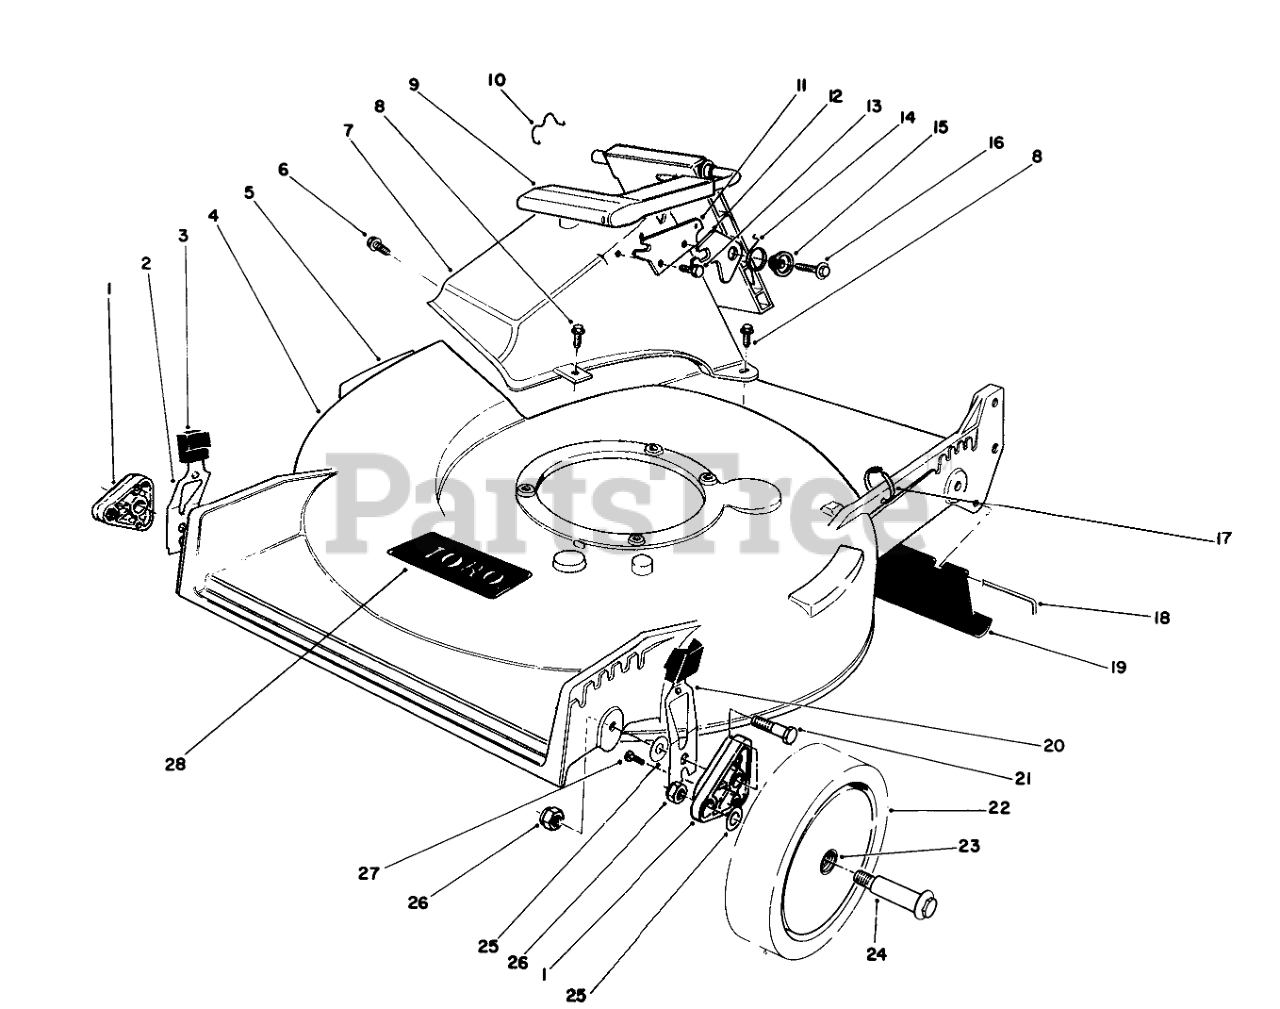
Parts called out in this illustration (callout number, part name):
1	ARM-PIVOT, FRONT
2	RH SPRING ARM ASSEMBLY
3	KNOB-ARM
4	Housing (Incl. Ref. #5)
5	DECAL-DANGER
6	SCREW AND WASHER ASM
7	Tunnel Discharge
8	SCREW-HWH
9	Discharge Door Assembly
10	DOOR RET SPRING
11	DOOR LATCH PLATE
12	SAFETY LATCH
13	SCREW-PLASTITE
14	TORSION SPRING
15	DOOR SPACER
16	SCREW-HWH
17	TIE-CABLE
18	Rod Shield
19	SHIELD - TRAILING
20	LH SPRING ARM ASSEMBLY
21	SCREW-SHOULDER
22	Wheel & Tire Assembly (Incl. Ref. #23)
23	BUSHING
24	WHEEL BOLT
25	WASHER
26	Nut
27	SCREW-HWH
28	DECAL
